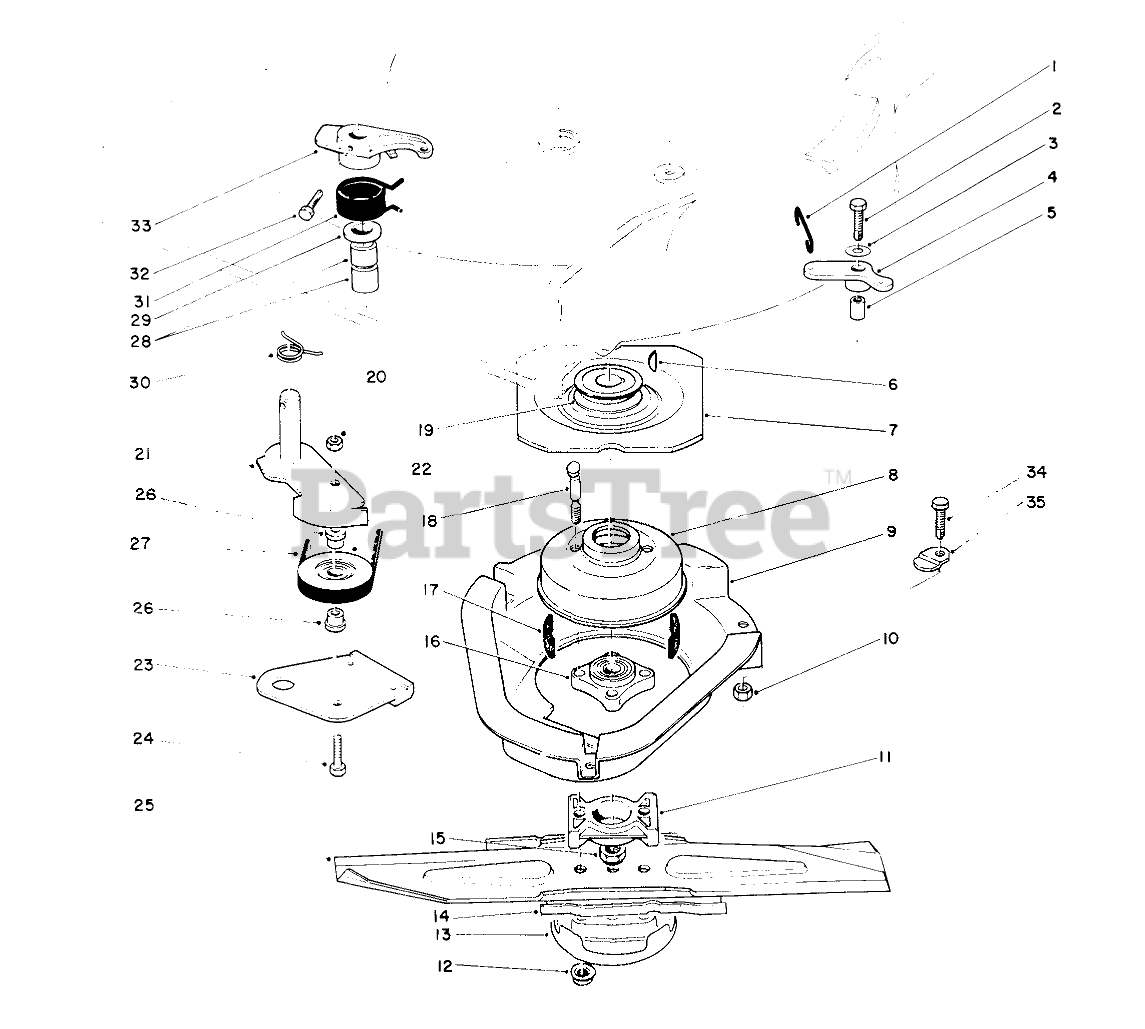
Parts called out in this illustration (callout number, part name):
1	LINK-CONTROL
2	SCREW-HH
3	WASHER-PLAIN
4	BELLCRANK
5	SLEEVE-BELLCRANK
6	KEY-WOODRUFF
7	Flywheel
8	Drum-Brake
9	Shield
10	NUT-LOCK, NI
11	SPACER-BLADE
12	NUT-LOCK
13	CUP-SCALP, ANTI
14	Accelerator
15	NUT-LOCK, NI
16	HUB ASM
17	DAMPENER-VIBRATION
18	BOLT-BLADE
19	PULLEY-DRIVER
20	NUT-LOCK, NI
21	ARM-IDLER
22	PULLEY-IDLER
23	BRAKE PLATE ASM
24	SCREW-HH
25	Blade
26	SPACER-PULLEY, IDLER
27	V-BELT
28	BEARING
29	WASHER
30	SPRING-TORSION
31	SPRING-TORSION
32	SCREW-HH
33	LEVER
34	SCREW-HH
35	SHIELD-RETAINER
